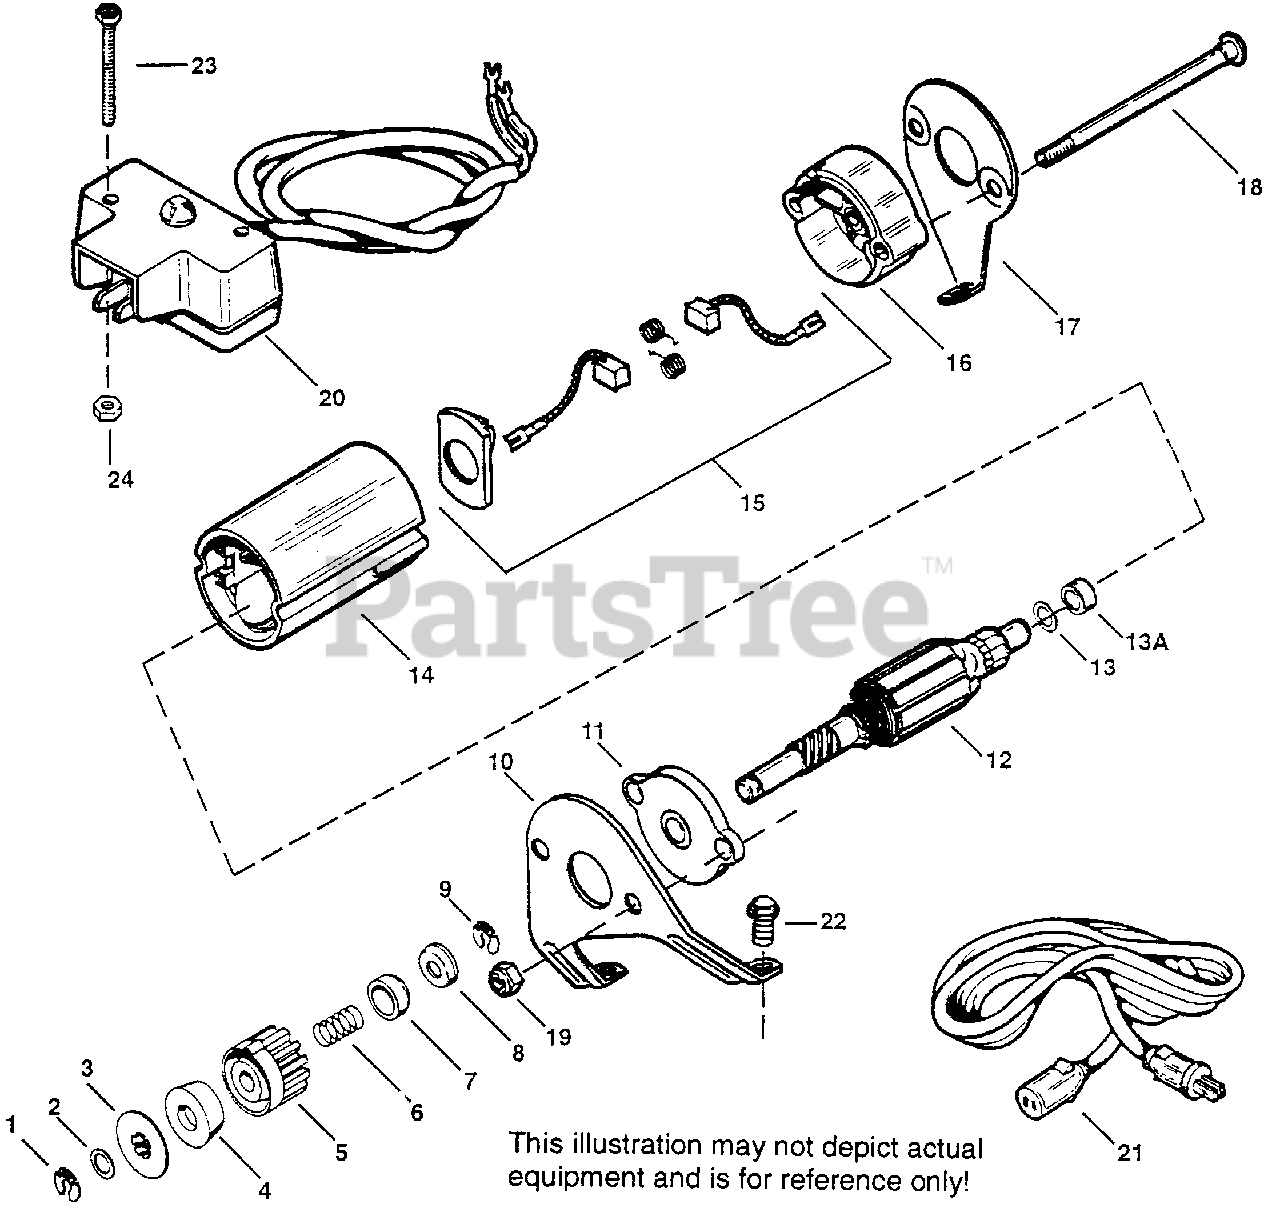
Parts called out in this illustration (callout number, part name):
1	Retainer Ring
2	Dust Washer
3	Pinion Driver
4	Anti-drift Spring
6	Anti-drift Spring
7	Spring Retainer
8	Cup Washer
9	Retainer Ring
21	Extension Cord (10'6")
22	Screw, T-30, 1/4-20 x 1/2"
23	Screw, 6-32 x 2-1/2"
24	Nut & Washer Ass'y.
